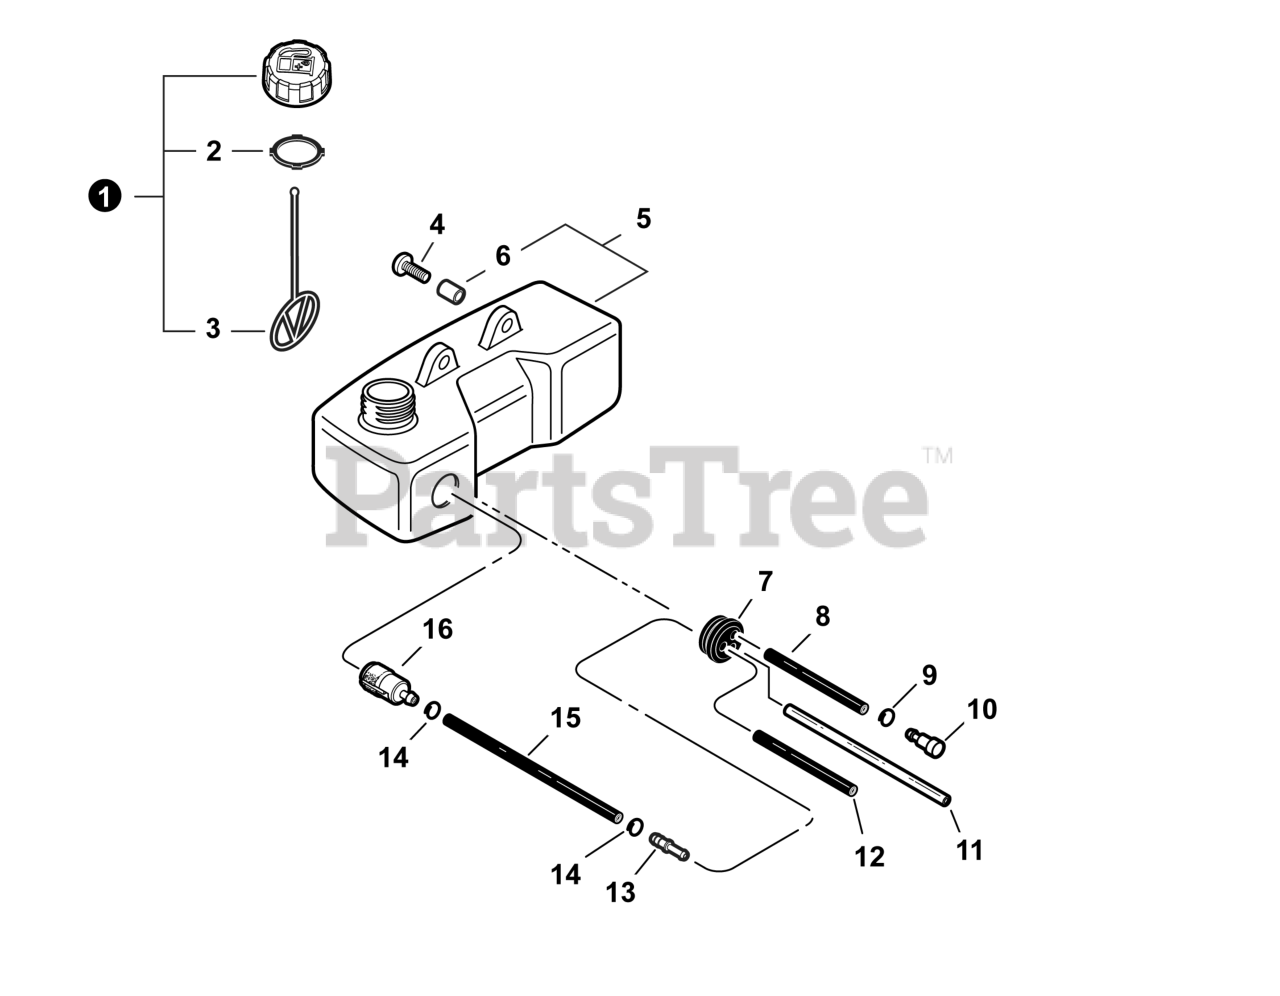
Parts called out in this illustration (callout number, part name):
1	CAP ASSY
2	GASKET, FUEL CAP
3	CONNECTOR, CAP L= 100 MM
4	SCREW 5x15
5	TANK ASSY, FUEL
6	SPACER 6.2x7.8x6
7	GROMMET, FUEL 5
8	PIPE, FUEL
9	CLIP 5.5
10	VENT ASSY
11	PIPE, FUEL 3x6x50 YELLOW
12	PIPE, FUEL 3x5x70 BLACK
13	CONNECTOR, PIPE 5x3.5
15	PIPE, FUEL 3x5x140 BLACK
16	FILTER, FUEL
